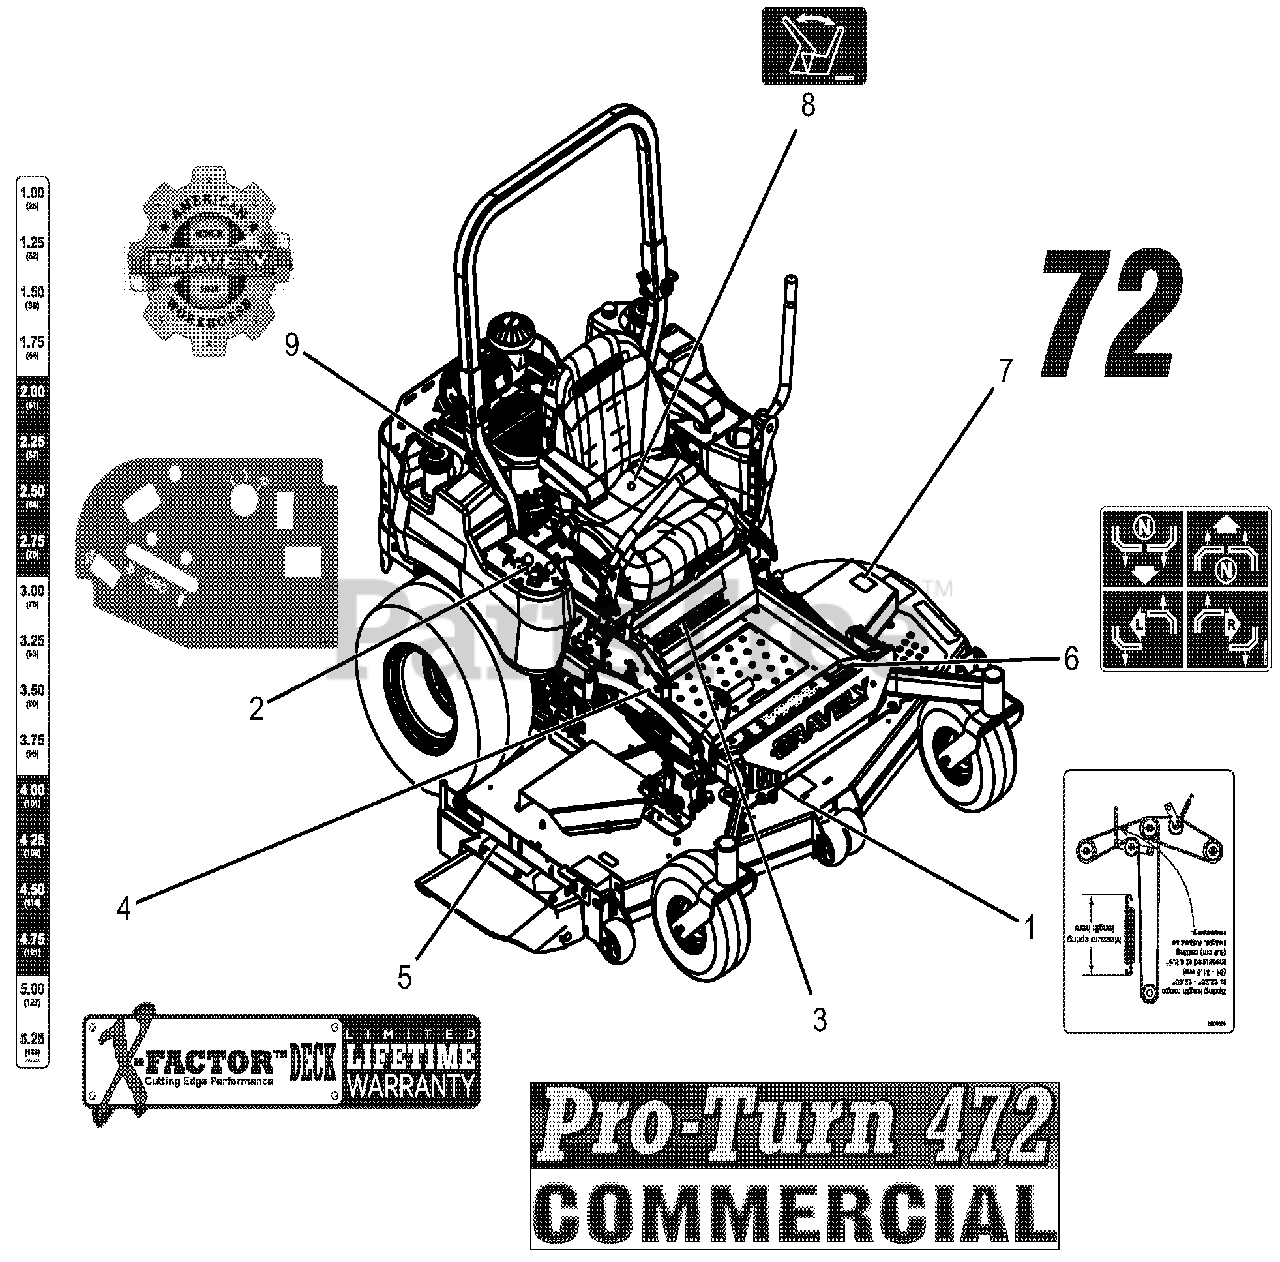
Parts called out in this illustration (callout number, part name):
1	DECAL, BELT DIAGRAM 60"
2	DECAL, CONTROL PANEL
3	DECAL, PRO-TURN 272
4	DECAL, PT400 HEIGHT OF CUT
5	DECAL, X-FACTOR DECK
6	DECAL, INSTRUCTIONAL - STEERING
7	DECAL, 72"
8	DECAL, SEAT RELEASE
9	DECAL, GRAVELY HERITAGE-LARGE
